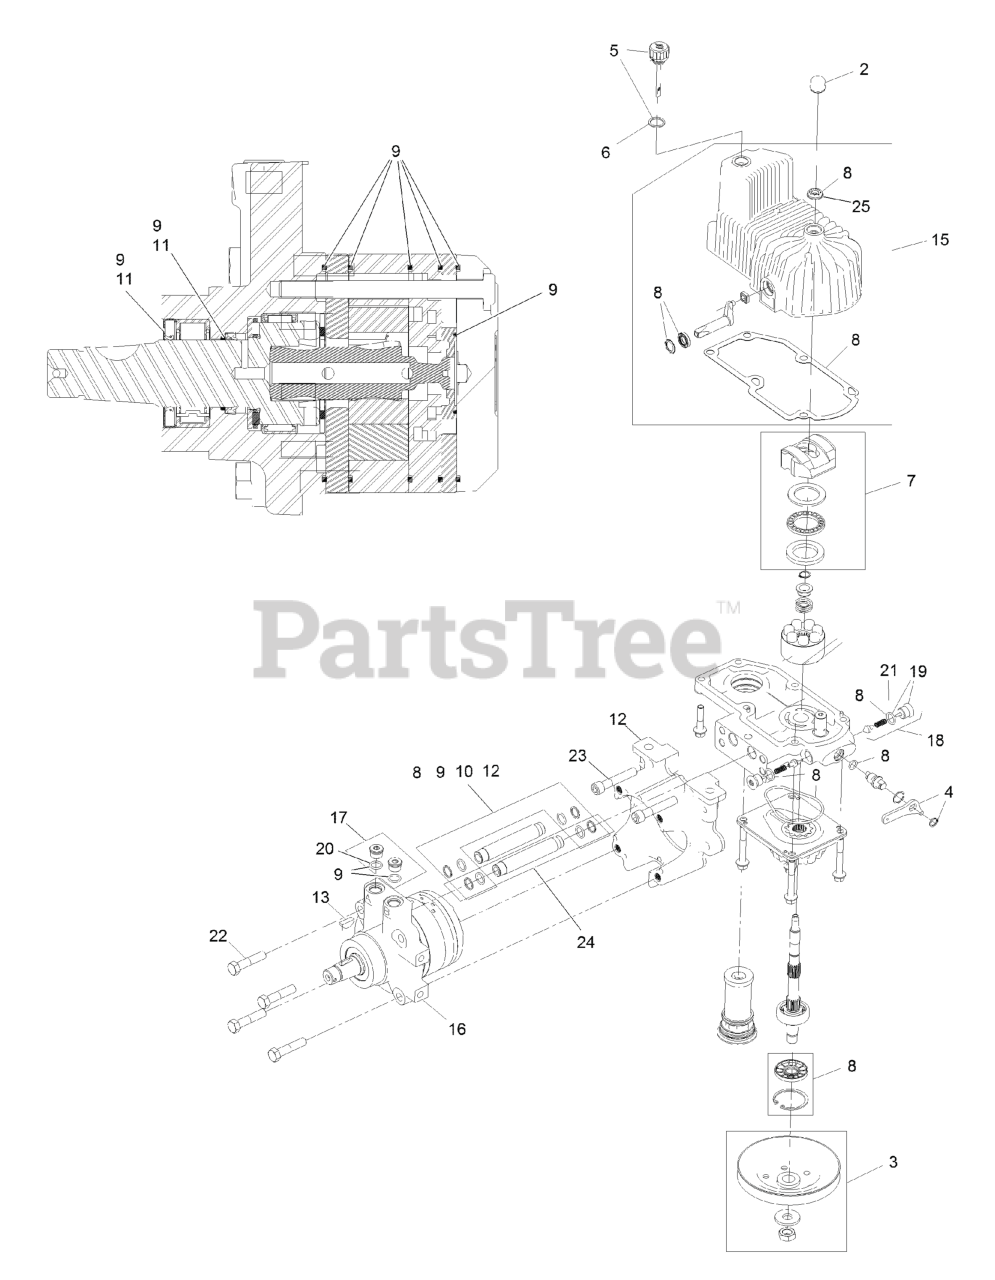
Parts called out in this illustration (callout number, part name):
2	FAN KIT
3	PULLEY KIT
4	HANDLE-BYPASS VALVE, HYDRO
5	DIPSTICK-HYDRO W/GASKET
6	GASKET-DIPSTICK, HYDRO
7	SWASH BLOCK KIT
8	PUMP SEAL KIT
9	MOTOR SEAL KIT
10	TUBE SEAL KIT
11	OUTPUT SHAFT SEAL KIT
12	NOSE CUP-UHT
13	KEY-WOODRUFF
15	HOUSING-HYDRO, LH
16	MOTOR-HYDRAULIC LH 240CC
17	MAGNETIC PLUGS SERVICE KIT
19	O-RING-CHECK VALVE
20	SCREW HH
21	SCREW-HSH
22	HYDRAULIC TUBE KIT
23	SHOCK VALVE, 12CC HYDRO
24	SEAL-FAN DRIVE
25	PULLER-PULLEY
26	ROTATING KIT
